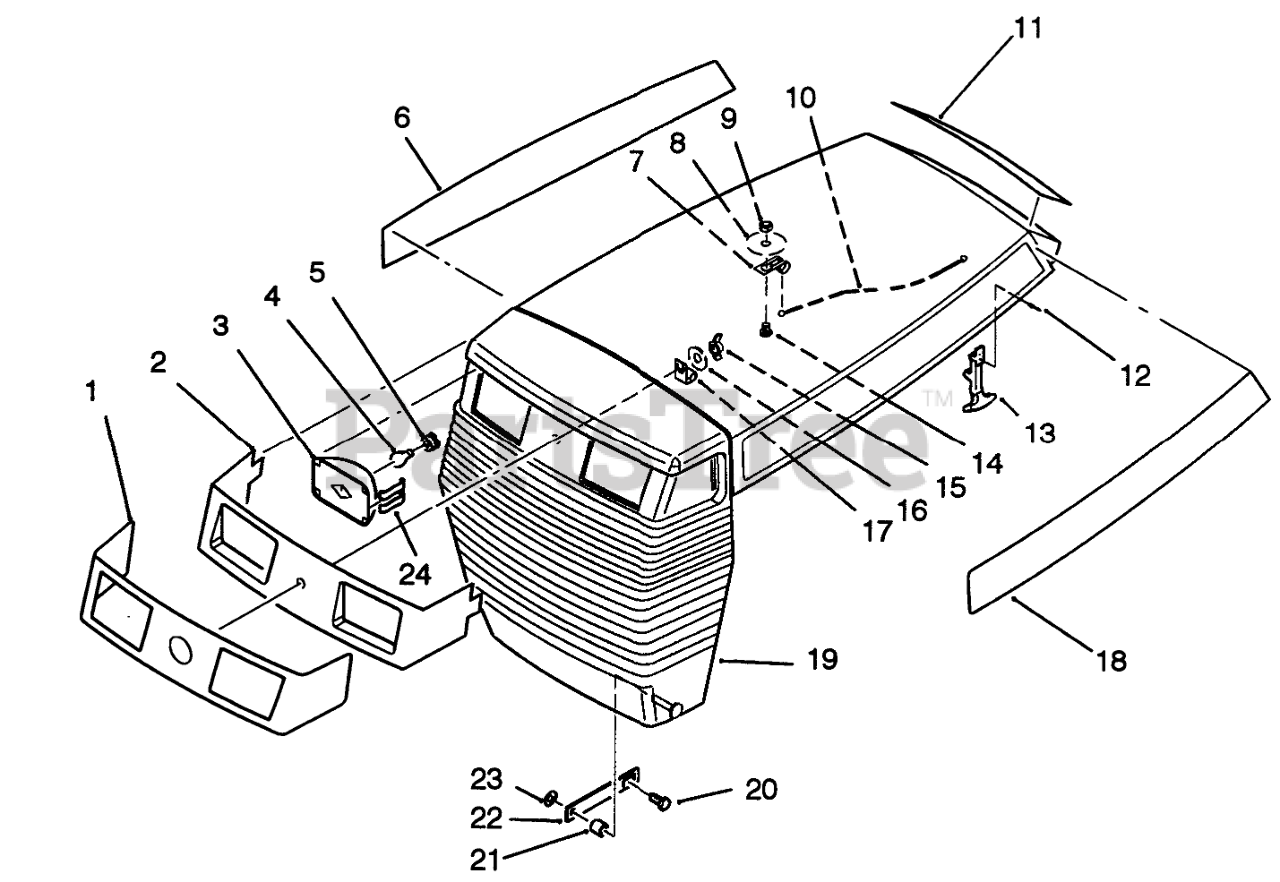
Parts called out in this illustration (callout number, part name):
1	DECAL-FRONT HOOD
2	LIGHT-BAR BLACK
3	LIGHT POD
4	BULB
5	SOCKET-HEADLIGHT
6	DECAL-HOOD 244-5 R H
7	CLEVIS
8	WASHER-BACKING
10	CABLE-ASS'Y
11	Decal-Hood Rear
12	RIVET-POP
13	KEEPER-LATCH
14	SCREW
15	WING NUT
16	WASHER
17	J-CLIP
18	DECAL-HOOD 244-5 L H
19	Hood
20	SCREW
21	SPACER
22	STRAP R
23	PUSH-NUT 5/16
24	RETAINER
